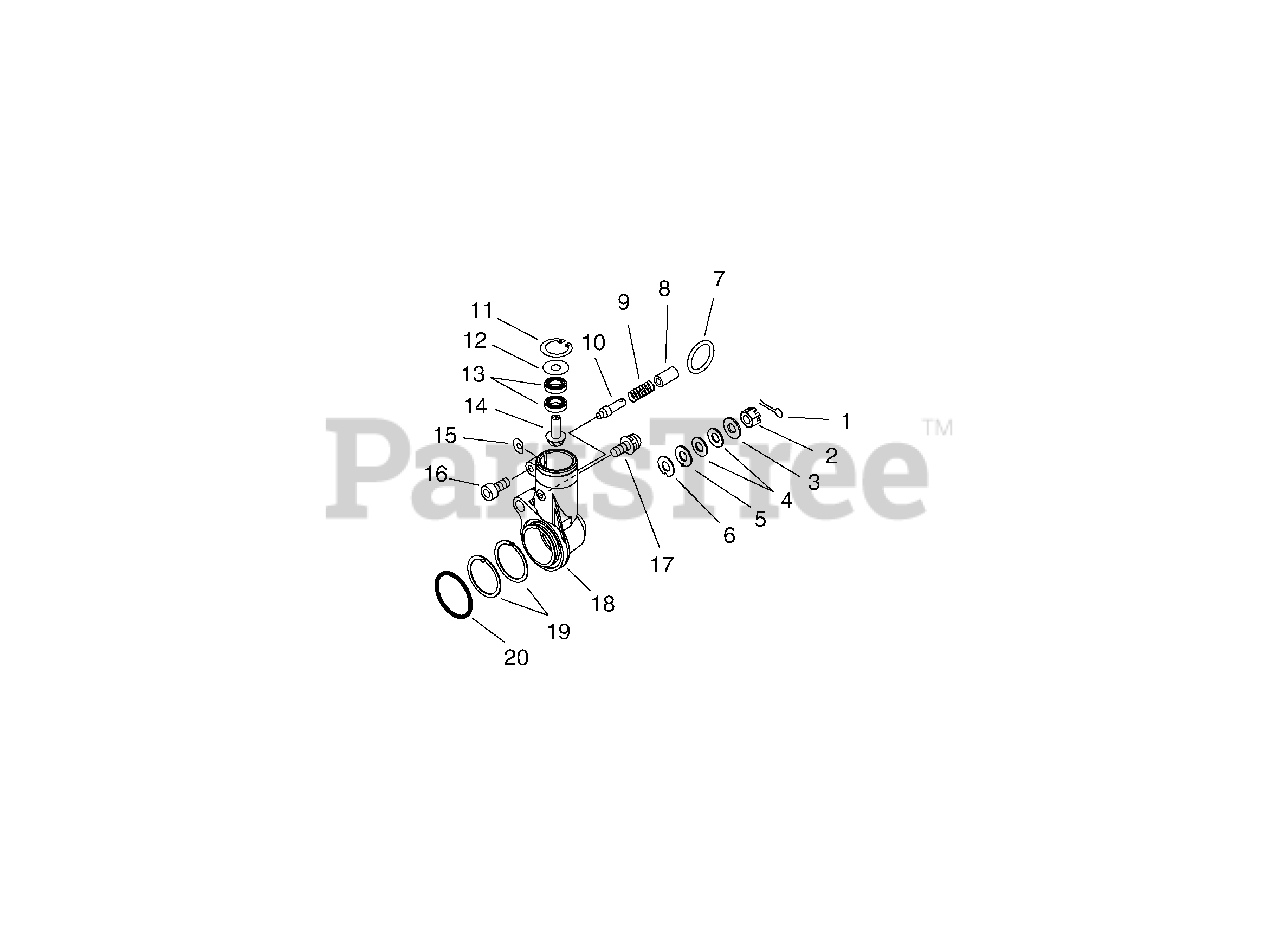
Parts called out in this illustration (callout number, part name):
1	PIN, COTTER 6×18
3	WASHER 8
4	WASHER, CONICAL
6	GASKET, GEAR CASE
7	RING, RETAINING
8	COLLAR 8
9	SPRING, COMPRESSION
10	LINCHPIN
11	RING, SNAP Ø22
12	RING, SNAP
13	BEARING, BALL 6900
14	GEAR, BEVEL
16	BOLT 5×25
17	SCREW 5×12
18	CASE, GEAR
20	O-RING 32
